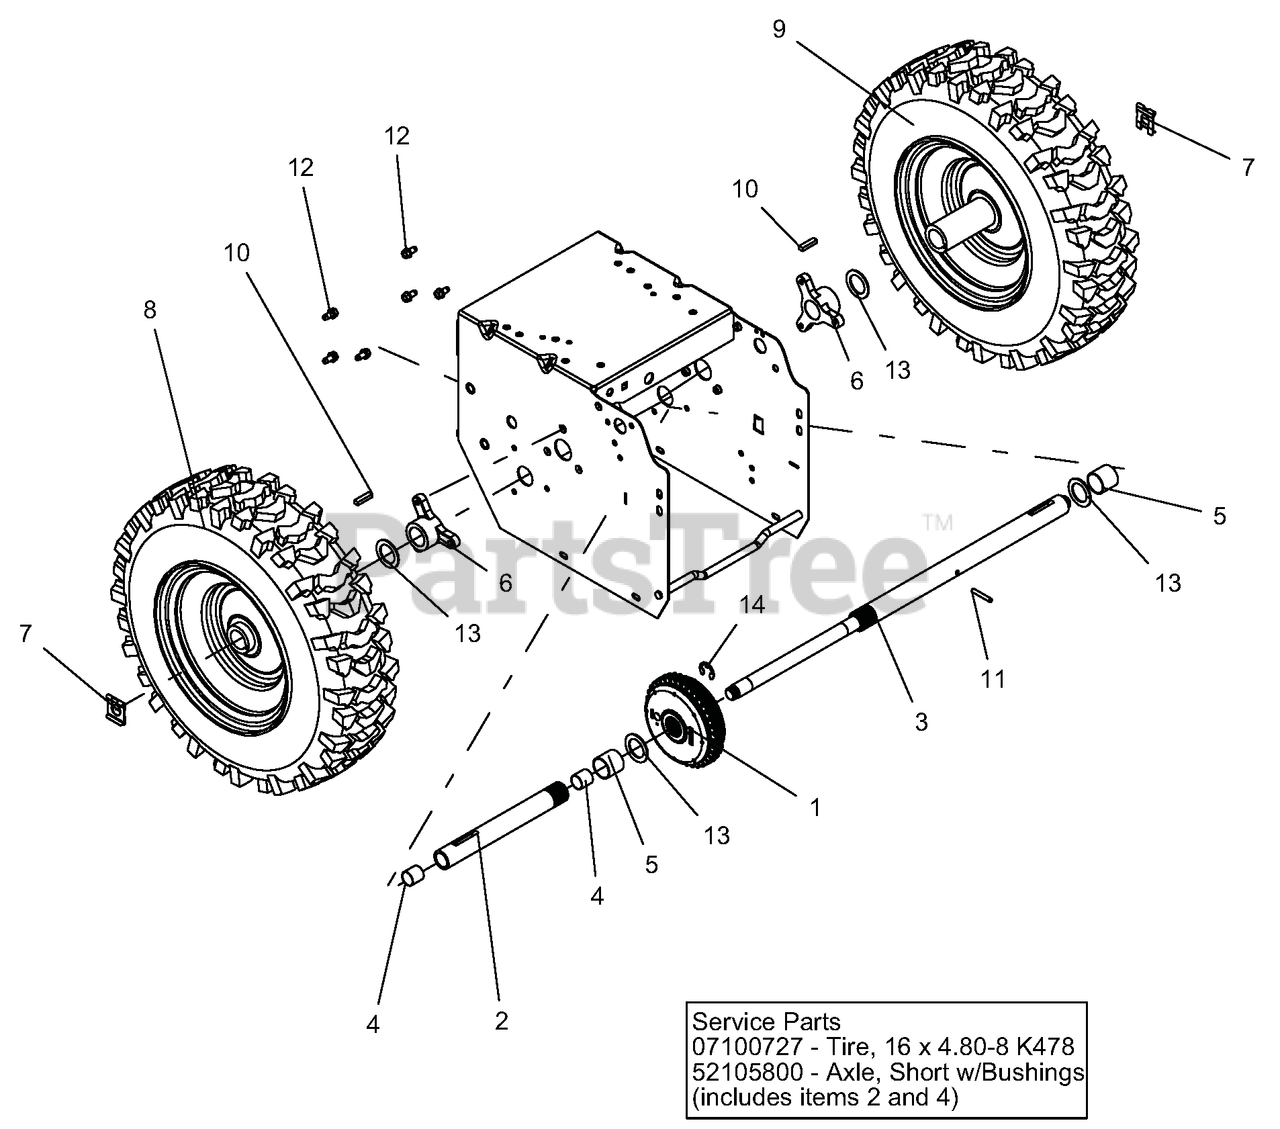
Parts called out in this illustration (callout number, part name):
1	DIFFERENTIAL, AUTOMATIC
2	AXLE, SHORT W/BUSHINGS
3	AXLE, LONG - DIFFERENTIAL
4	BSHG-SLV .706X.764X.75 BRZ
5	BSHG-SLV, 1.012X1.125X1.00
6	BUSHING, AXLE
7	CLIP, SNAP .625 DIA
8	TIRE/WHEEL,RH 16X4.8-8 DIFF T2
9	TIRE/WHEEL,LH 16X4.8-8 DIFF T2
10	KEY-RECT .25X.188X1.00
11	PIN-ROLL .188X1.25
12	SCR-TAP .25-20X.50 HWH TR YWZ
13	WSHR-FL-STL 1.010X1.505X.062YZ
14	RG-RTNG-EXT .625X.042
